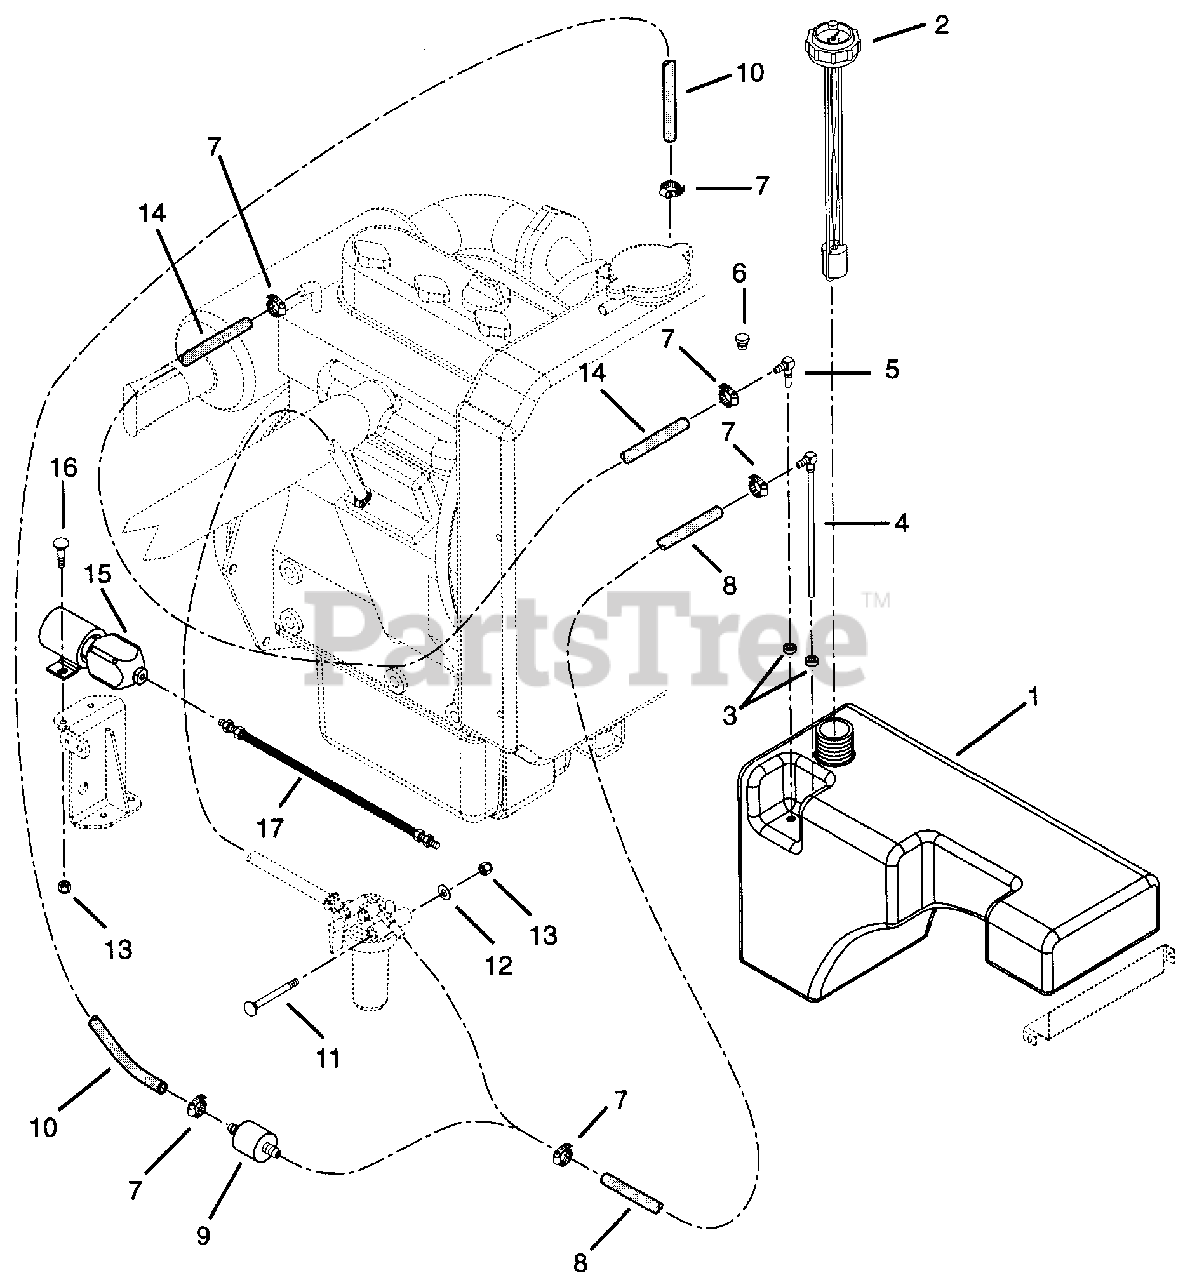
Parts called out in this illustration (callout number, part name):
1	Tank,Fuel
2	Gauge,Fuel
4	Fitting,Tank
5	Fitting-Tank 1.37 x .406
6	Plug,Fuel Tank Bushing
7	Hose Clamp
8	Hose, Fuel .312 Inside Diameter x 6
9	Filter,Fuel
10	Hose, Fuel, .312 Inside Diameter x 14
11	Bolt-Hex .25-20 x 2.75
12	Washer-Flat-Steel .281 x .620 x .065
13	Nut-Locking-Nylon .250-20 Grade 2
14	Gas Line - Bulk
15	Fuel Stop Solenoid - Diesel
16	Bolt-Hex .25-20 x .75 Grade 5
17	Cable Assembly, Fuel Stop Solenoid
